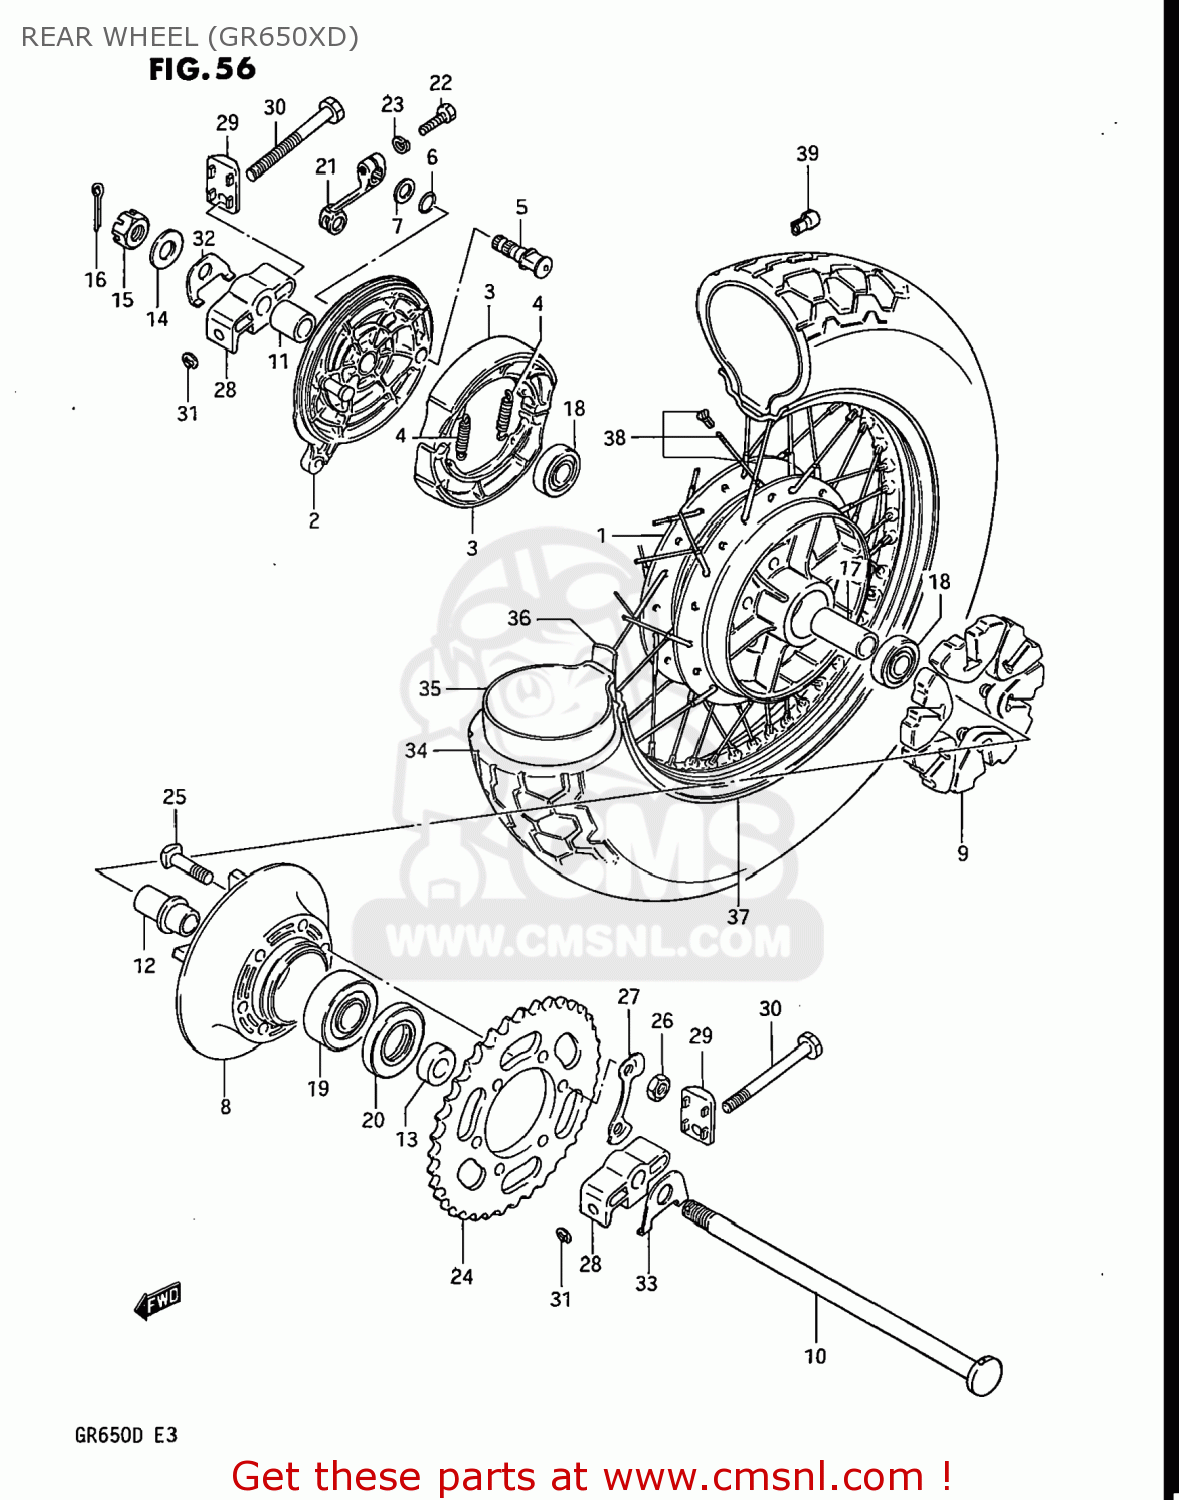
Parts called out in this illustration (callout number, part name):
1	DRUM,REAR HUB
2	PANEL,REAR HUB
3	SHOE,BRAKE
4	SPRING,BRAKE SHOE
5	CAM,FRONT BRAKE
6	O-RING,BOSS
7	WASHER (15X24X1.6)
8	DRUM,REAR SPROCKET MOUNT
9	ABSORBER,REAR HUB SHOCK
10	AXLE,REAR
11	SPACER (17.5X28X35)
12	RETAINER,RR SPROCKET DRUM
13	SPACER (17X33X12.5)
14	WASHER (17X30X3.2)
15	NUT
16	PIN,COTTER
17	SPACER(17.5X25X70)
18	BEARING
19	BEARING
20	SEAL,OIL(33X62X7)
21	LEVER,REAR BRAKE CAM
22	BOLT
23	LOCK WASHER
24	SPROCKET,REAR
25	BOLT
26	NUT
27	WASHER
28	BODY,CHAIN ADJUSTER
29	PLATE,CHAIN ADJUSTER
30	BOLT,CHAIN ADJUSTER
31	E RING
32	WASHER,CHAIN ADJUSTER
33	WASHER,CHAIN ADJUSTER
34	TIRE
35	TUBE ASSEMBLY,WHEEL,INNER
36	PROTECTOR,INNER TUBE
37	RIM,REAR WHEEL (2.50X16)(
38	SPOKE SET,REAR
39	BALANCER,WHEEL (B)
